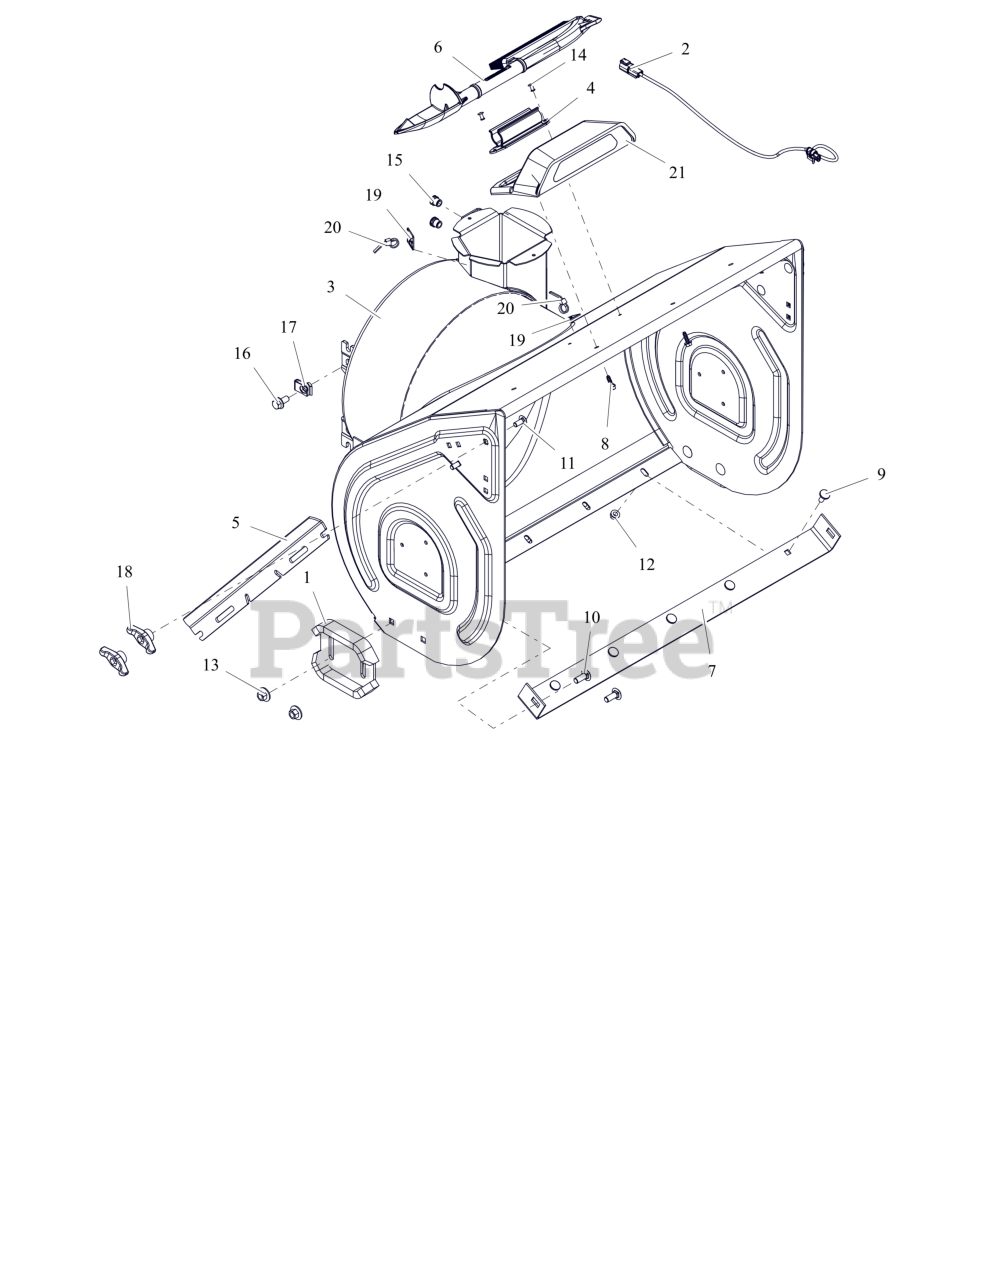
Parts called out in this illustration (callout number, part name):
1	RUNNER, SKID SHOE
2	HARNESS- WIRE - LIGHT JUMPER
3	HOUSING, PRO W/DECAL 28"
4	MOUNT, SNOW CLEAN OUT
5	CUTTER, DRIFT
6	DEVICE, SNOW CLEAN OUT W/BRUSH
7	BLADE, SCRAPER-28"
8	SCR, PLASTITE .25-10X.75 ZCC
9	BOLT, MODIFIED HEAD CARRIAGE
10	BLT,RHSSN .38-16X1.00 G5 ZCC
11	BLT, RHSSN.31-18X.750 G5 ZCC
12	NUT-LK-TOP-FLG .312-18 GF ZCC
13	NUT- CON-LN .375-16 ZC120
14	RIVET, #66 STEEL POP PD BLACK
15	NUT,THD,INSERT .38-16 ZC120
17	NUT-RTNR .375-16X.37
18	KNOB,WING .31-18 UNC NYL/TALC
19	MOUNT, CABLE-TIE DOWN
20	CABLE TIE LG 5-1/2
21	HOUSING, LIGHT - LED
